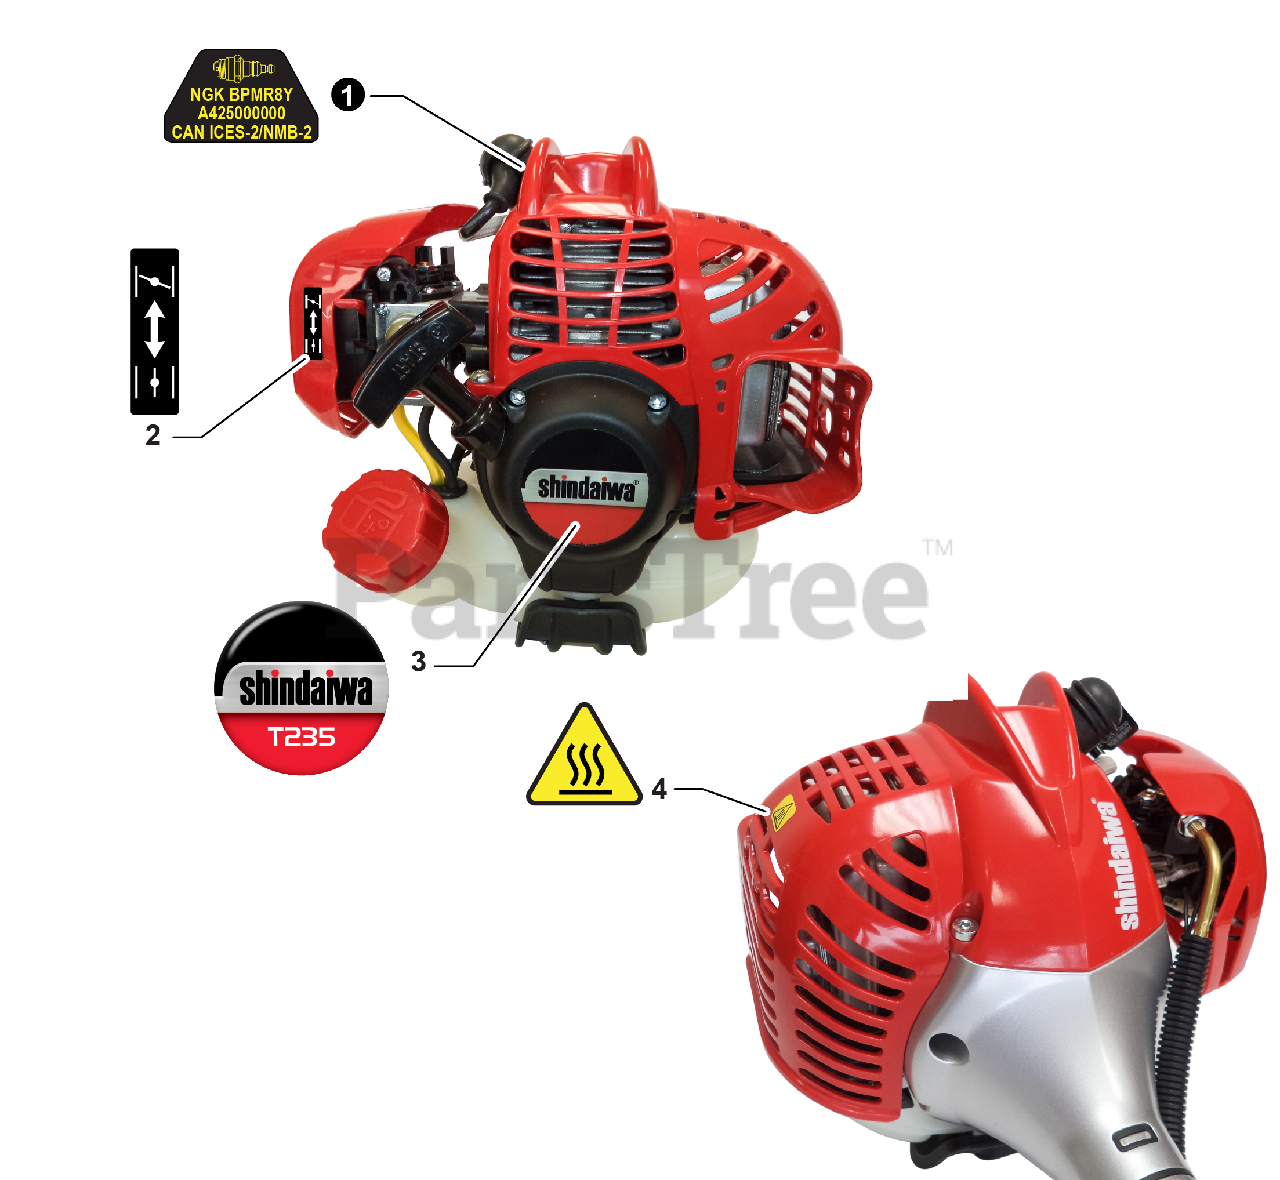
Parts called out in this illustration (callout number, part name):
1	LABEL - SPARK PLUG - BPMR8Y
2	LABEL - CHOKE
3	LABEL - SHINDAIWA - T235
4	LABEL - CAUTION - HOT
